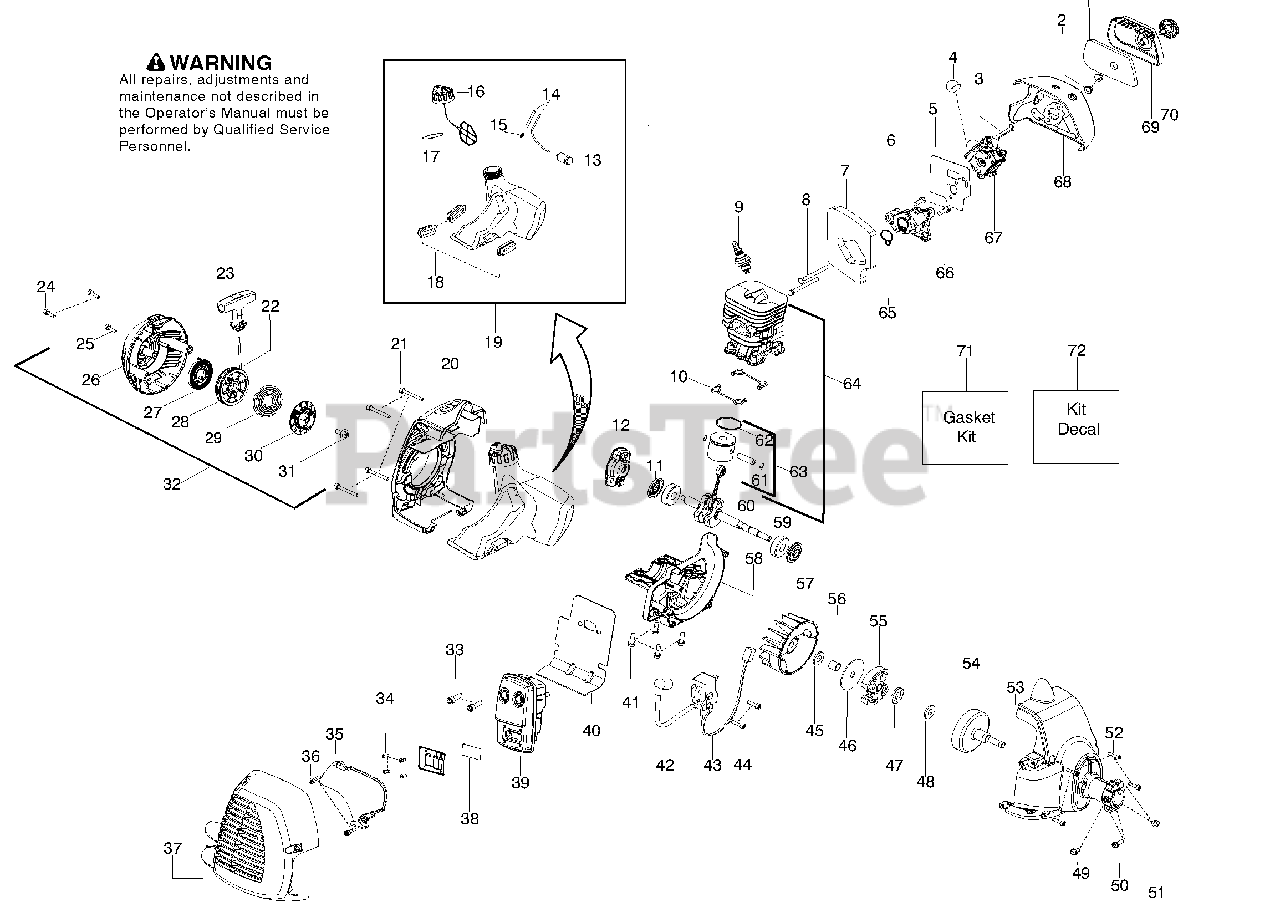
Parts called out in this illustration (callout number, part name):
2	Nut-Carb. Screw
3	Lever - Choke
4	Bulb-Purge
5	Kit-Carb. Gasket
6	Adaptor-Carb.
7	Foam-Gasket (kit)
9	Plug-Spark (RCJ-8Y)
10	Seal-Cylinder (kit)
11	Seal-Crankshaft (kit)
12	Assy-Starter Pawl
13	Assy-Fuel Filter
14	Kit-Fuel Line
15	Fitting-Fuel line
16	Assy-Cap w/ret.
17	O-ring - Fuel Cap (kit)
18	Isolator-Fuel Tank
19	Kit-Fuel Tank Assy.
20	Shroud-Rear (KIT)
22	Kit-Rope
23	Handle-Starter
26	Hsg.-Starter (KIT)
27	Kit-Spring
28	Kit-Starter Pulley
29	Spring - Driver
30	Pulley-Driver
32	Assy-Starter Hsg.
33	Bolt-Muffler
34	Screw
35	Shield-Heat
37	Kit - Muffler Guard
38	Kit-Spark
39	Kit-Muffler
40	Gasket-Paper Met.(kit)
43	Assy-Leadwire
46	Washer-Clutch
47	Bearing - Thrust
48	Washer - Thrust
49	Screw
50	Screw
53	Assy-Fan Housing
54	Assy-Clutch Drum
55	Assy-Clutch
58	Crankcase-Cast
60	Assy-Crankshaft
61	Retainer-Piston Pin
62	Ring-Piston
63	Kit-Piston
64	Kit-Piston/Cyl.
65	Seal-adaptor (kit)
67	Kit-Carb.
68	Airbox
69	Cover-Air Box
71	Kit-Gasket
72	Kit - Decal
